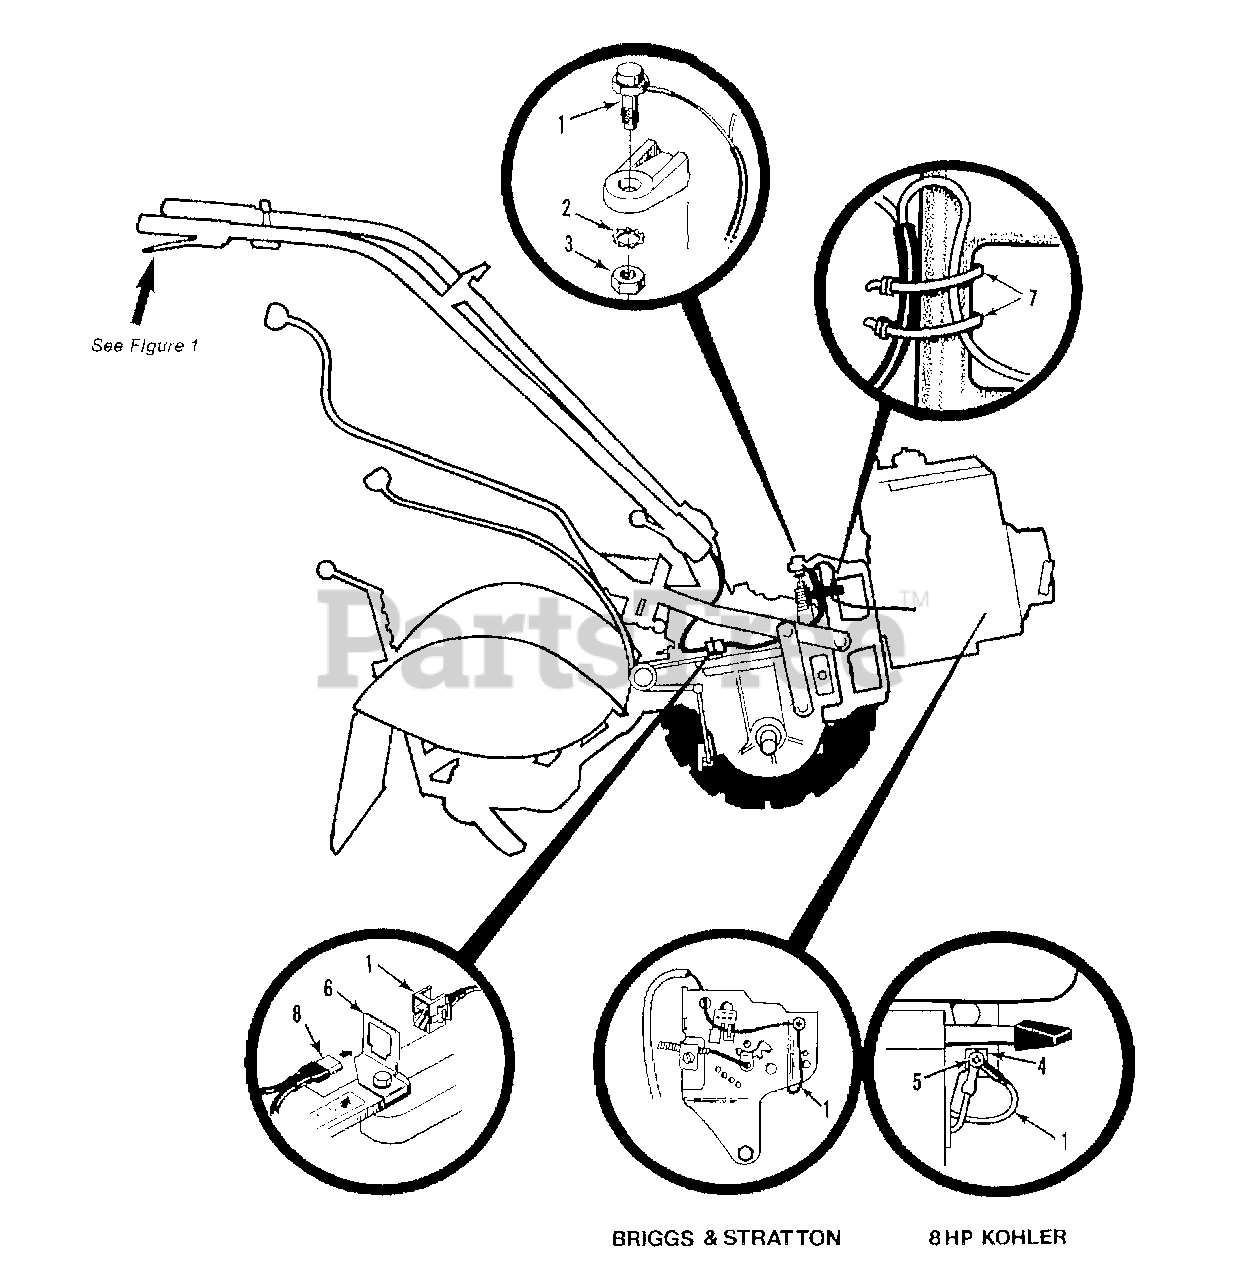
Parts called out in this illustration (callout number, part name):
1	HARNESS-WIRE ENG OPC
2	WASHER-LK .438 EXT TOOTH
3	NUT-HEX/JAM 7/16-20
4	GROMMET-7 T/L & 8 KOH OPC
5	SCR #8-18 SELF TAP
6	CLIP-CONNECTOR
7	TIE-RED
8	HARNESS-WIRE OPC HORSE
